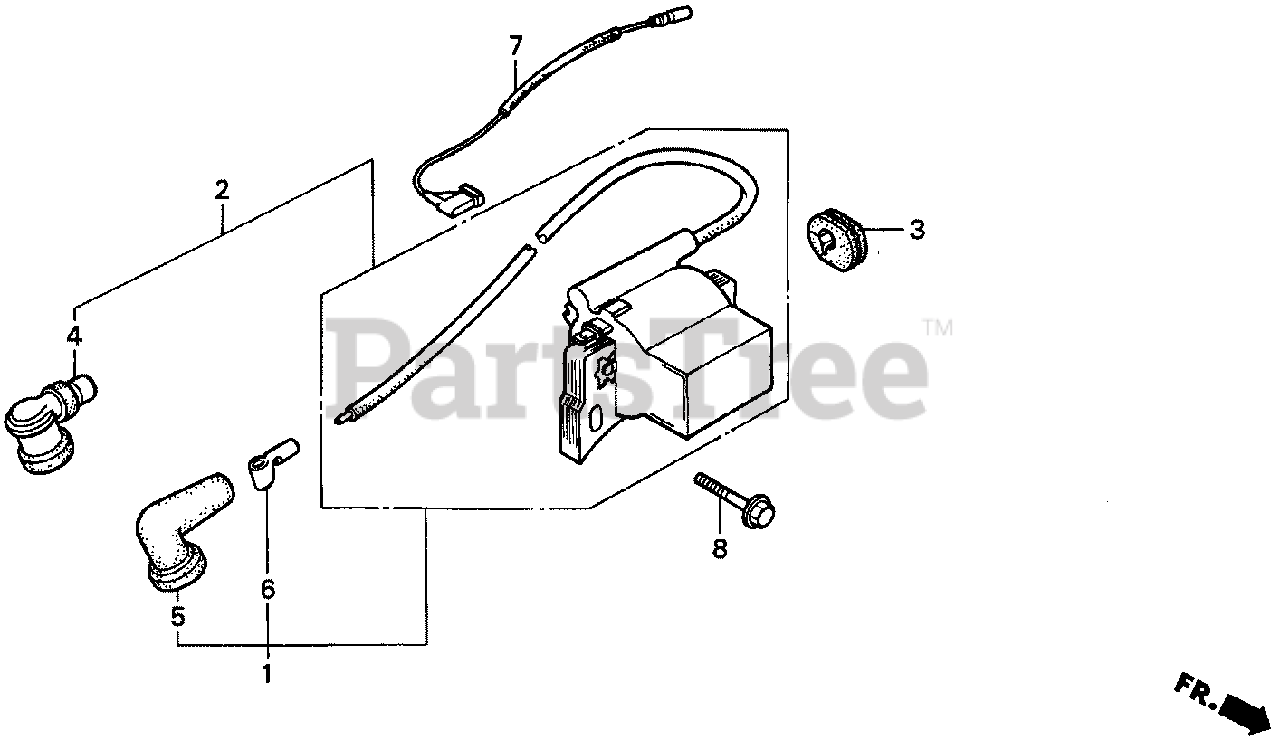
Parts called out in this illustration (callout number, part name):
2	COIL ASSY., IGNITION
3	GROMMET, IGNITION WIRE
4	CAP ASSY., NOISE SUPPRESSOR
7	WIRE, STOP SWITCH
8	BOLT, FLANGE (6X25)
